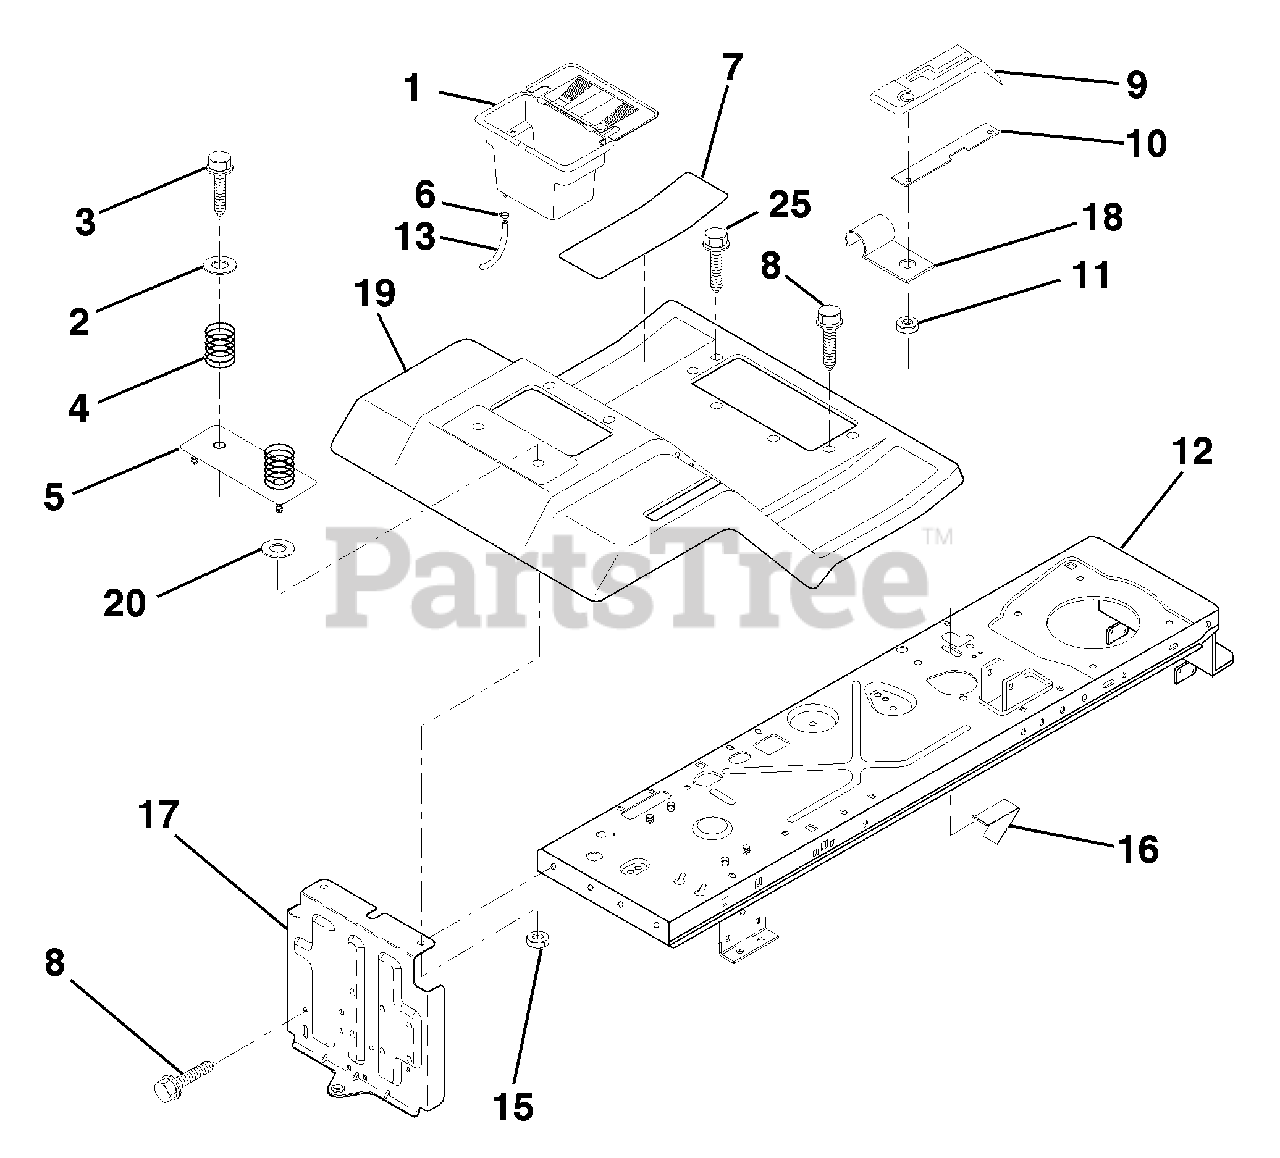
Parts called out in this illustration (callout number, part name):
1	Case, Battery
2	Washer 13/32 x 1-1/4 x 12 Ga.
3	Screw, Hex Wsh. Thrdrol. 3/8-16 x 3/4
4	Spring, Compression, Seat
5	Plate, Asm. Battery
6	Clamp, Hose
7	Pad, Footrest
8	Screw, Hex Wsh Thdrol. 5/16-18 x 3/4
9	Console, Shift Control
10	Bar, Shift Lock
11	Nut, Self-Thrd., Wsh. Head 3/16
12	Assembly, Frame
13	Tube, Battery Drain
15	Nut, Keps Hex 1/4-20 UNC
16	Switch Actuator
18	Clip, Insulated
19	Fender/Footrest
20	Washer 9/32 x 7/8 x 13 Ga.
25	Screw Hex Wsh Thdroll 5/16-18 x 1
